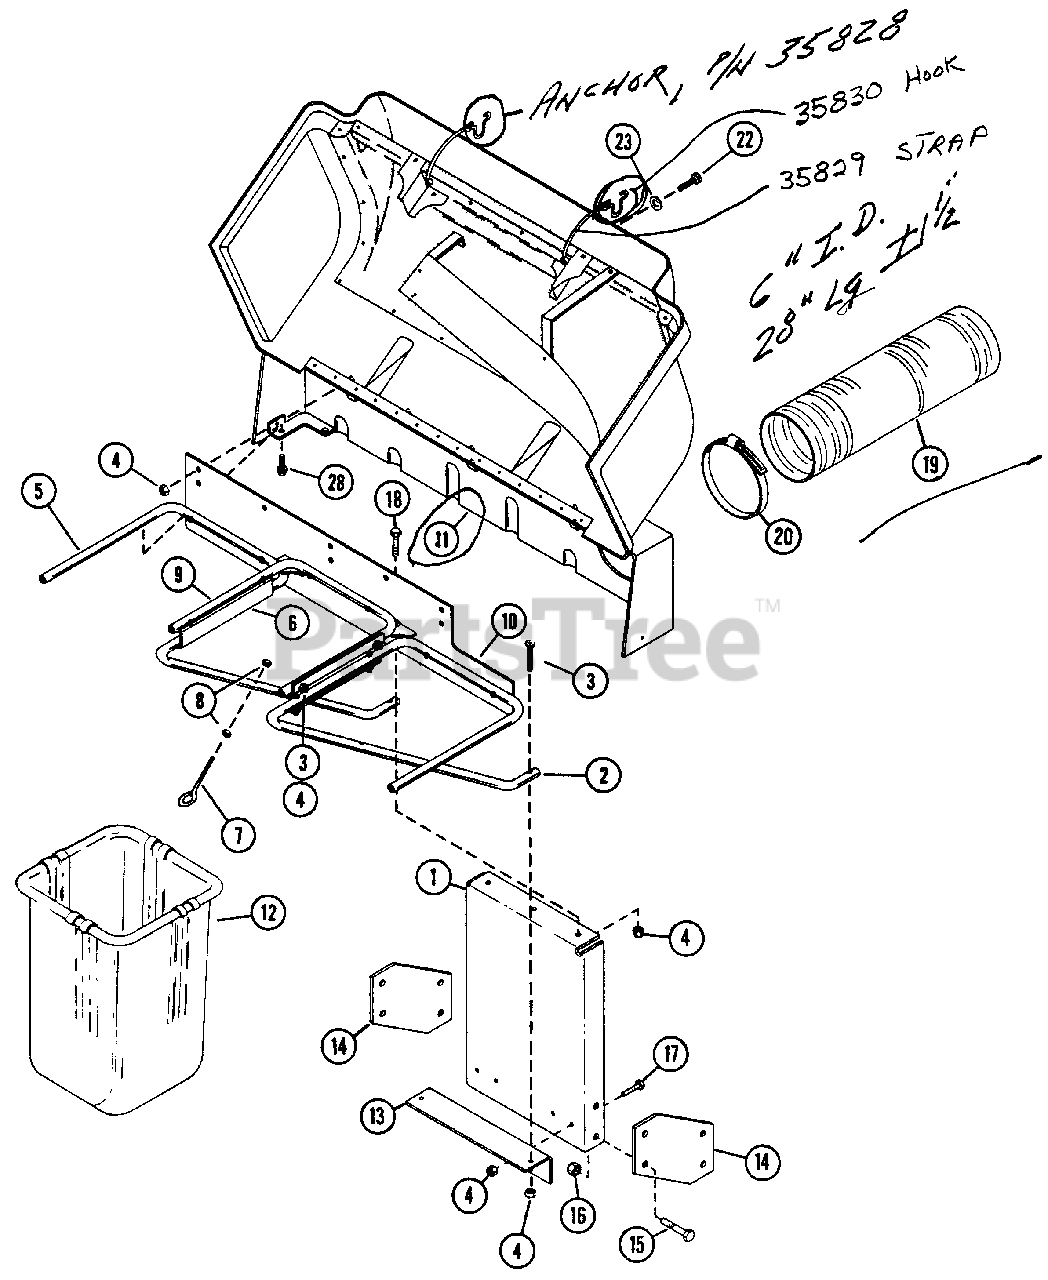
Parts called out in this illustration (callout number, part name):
1	SUPPORT
2	RIGHT TUBE
3	SCREW, MACHINE 5/16-18X1.50
4	NUT, LOCK 5/16-18
5	LEFT TUBE
6	TUBE BRACKET
7	EYEBOLT
8	NUT, LOCK 1/4-20
9	CENTER TUBE
10	MOUNTING BRACKET
11	COVER ASSEMBLY
12	GRASS BAGGER BASKET
13	BRACKET
14	RISER
15	BOLT, HEX 1/2-13X1.25
16	NUT, LOCK 1/2-13
17	BOLT, HEX 5/16-18X.75
18	BOLT, HEX 5/16-18X1.00
19	HOSE
20	HOSE CLAMP
21	BOLT, HEX 5/16-18X.50
22	SCREW, MACHINE 5/16-18X.75 T/HD
23	WASHER, .339/.359X1.125X.063 PL
